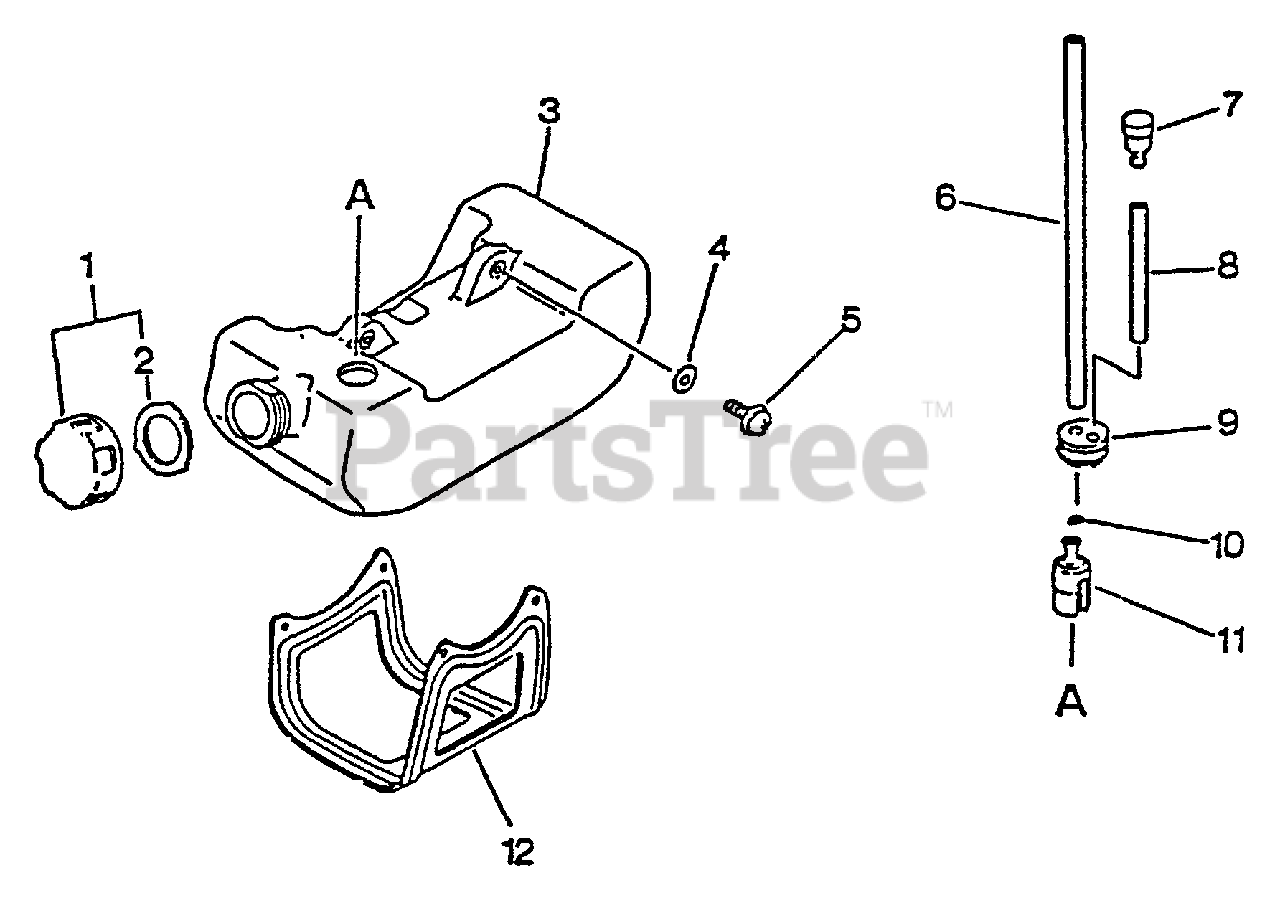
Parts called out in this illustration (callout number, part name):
1	CAP ASSY
2	GASKET, CAP
3	TANK, FUEL
4	WASHER - 5
5	SCREW - 5X16
6	PIPE - 3X5X180 -- BLACK
7	VENT, FUEL TANK
8	PIPE - 3X5X70 -- BLACK
9	GROMMET
10	CLIP - 6
11	FILTER, FUEL
12	GUARD, FUEL TANK
